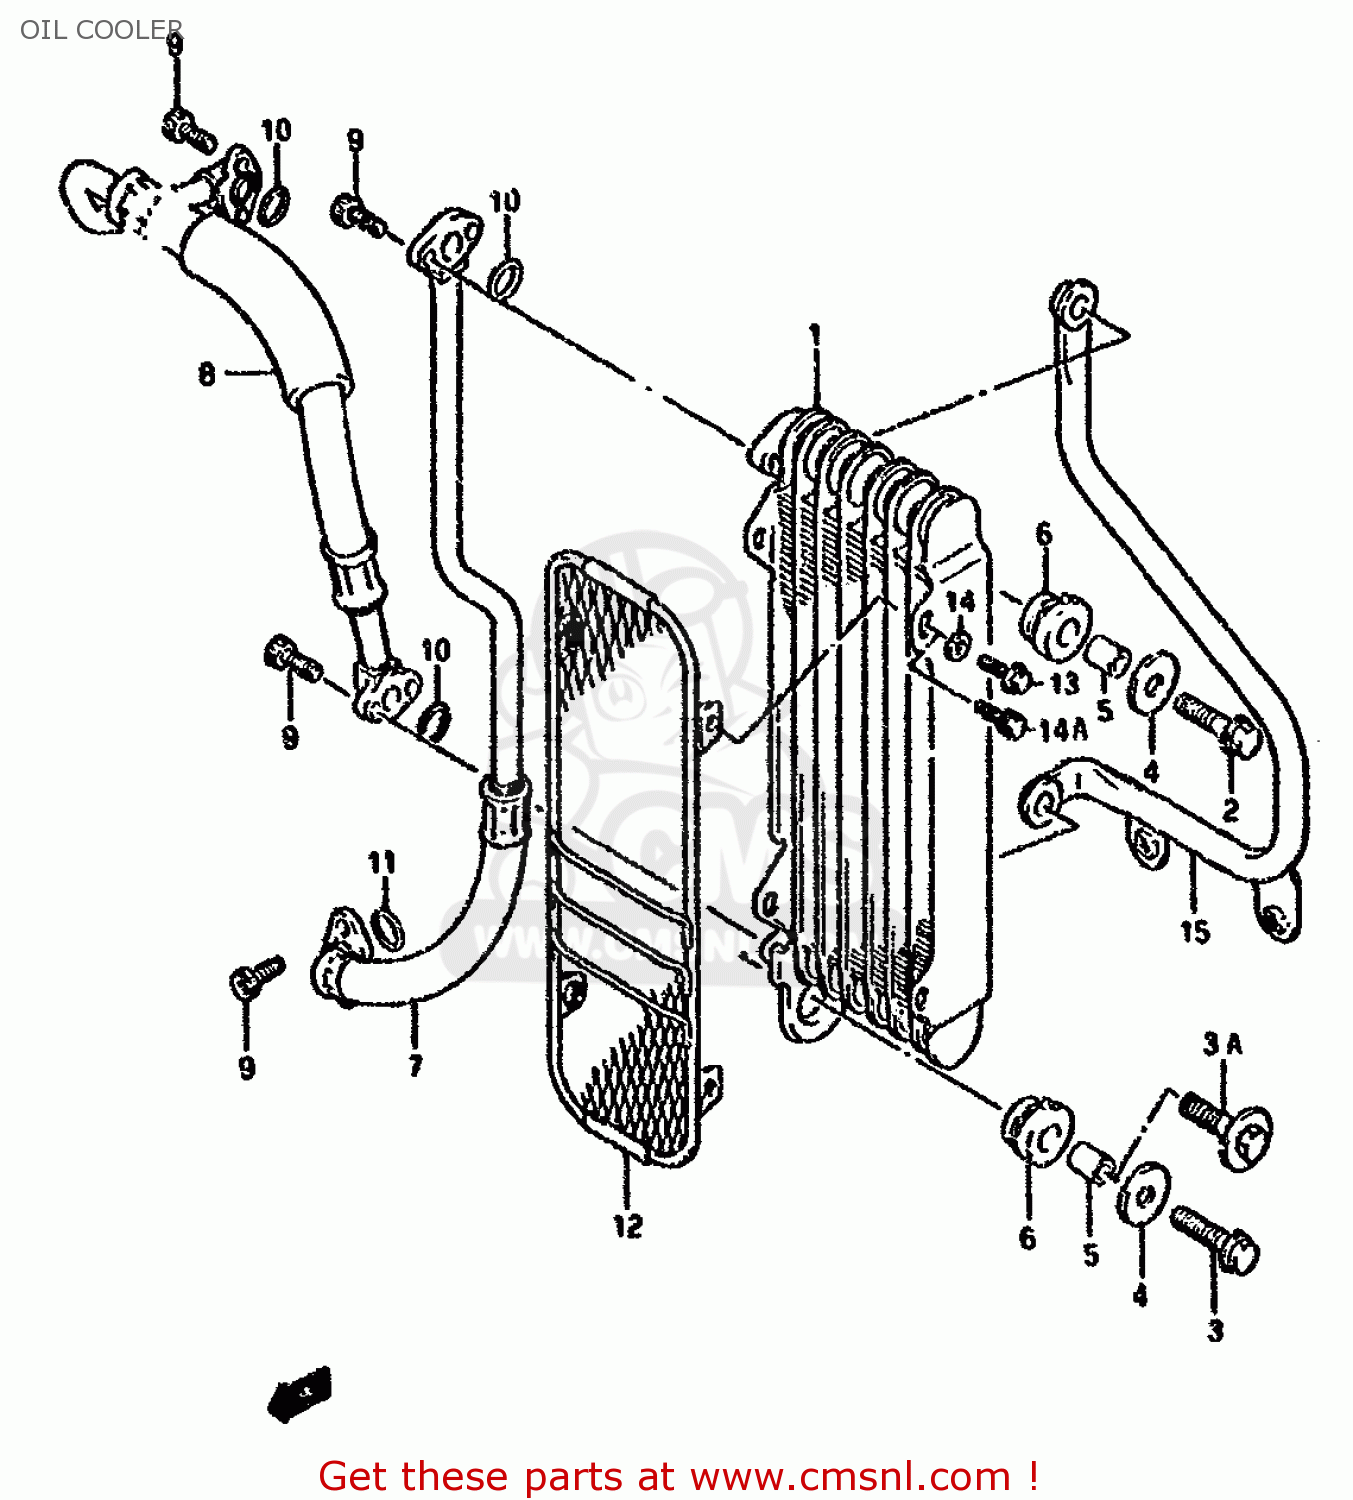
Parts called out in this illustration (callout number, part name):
1	COOLER ASSY,OIL
2	BOLT
3	BOLT
3A	BOLT(8X45)
4	WASHER (8.5X20X1.6)
5	SPACER (8.2X12X17)
6	CUSHION,OIL COOLER
7	HOSE,OIL COOLE
8	HOSE, OIL COOLER NO.2
9	BOLT
10	O RING(D:2.4,ID:12.3)
11	O RING,HEAD GASKET
12	BUMPER,OIL COOLER
13	BOLT
14	WASHER,LOCK
14A	BOLT
15	GUARD, OIL COOLER
